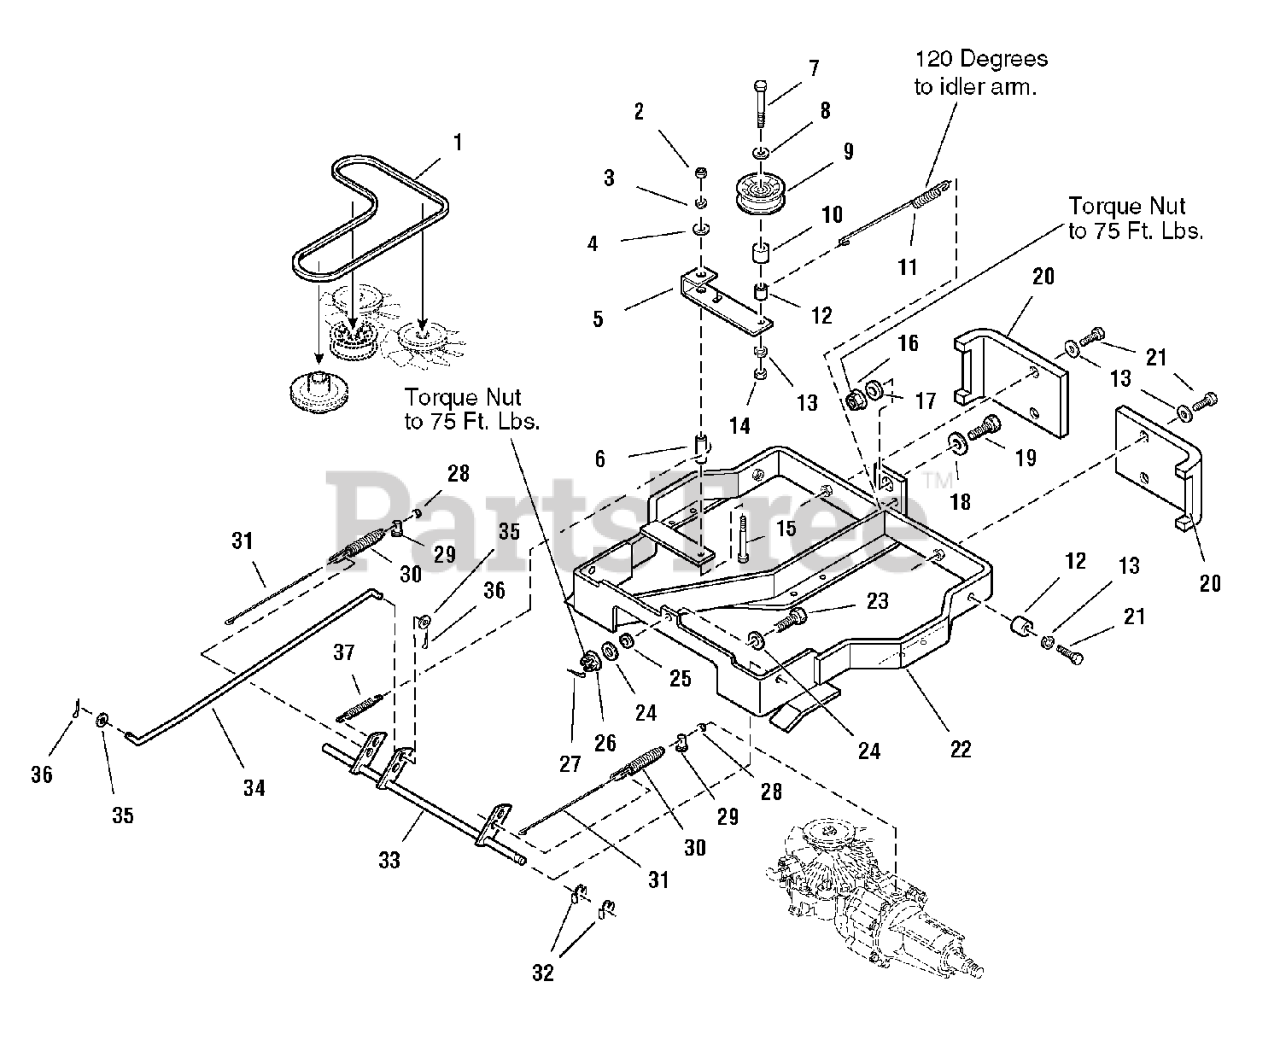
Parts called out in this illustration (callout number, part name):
2	NUT, Hex, 5/16-18
3	LOCKWASHER, Spring, 5/16
4	WASHER, 5/16
5	ARM, Idler
6	SPACER, Powdered Metal
7	CAPSCREW, Hex Head, 3/8-16 x 2-3/4, G8
8	WASHER, 3/8
9	PULLEY, Idler
10	SPACER, Powered Metal
11	SPRING, Extension
13	LOCKWASHER, Spring, 3/8
14	NUT, Hex, 3/8-16
15	CAPSCREW, Hex Head, 5/16-18 x 2-1/2, G5
16	NUT, Hex Flange, Two-Way Lock, 1/2-13
18	WASHER, 1/2
19	CAPSCREW, Hex Head, 1/2-13 x 1-1/4, G5
20	BUMPER, Weight, Cast Iron
21	CAPSCREW, Hex Head, 3/8-16 x 2, G5
22	FRAME ASSEMBLY, Transmission
23	CAPSCREW, Hex Head, 1/2-20 x 1-3/4, G8
24	WASHER, Spring, 1/2
26	NUT, Hex Slotted, 1/2-20
27	PIN, Cotter, 1/8 x 1-1/2
28	NUT, Hex Lock
29	PIN, Yoke
30	SPRING, Extension
31	ROD, Brake, 10-24 x 1-1/8
32	RING, Klipring Extension for 1/2 Diameter Shaft
33	SHAFT & ARMS ASSEMBLY, Pivot
34	ROD, Clutch
35	WASHER, 5/16
36	PIN, Cotter
37	SPRING, Extension
